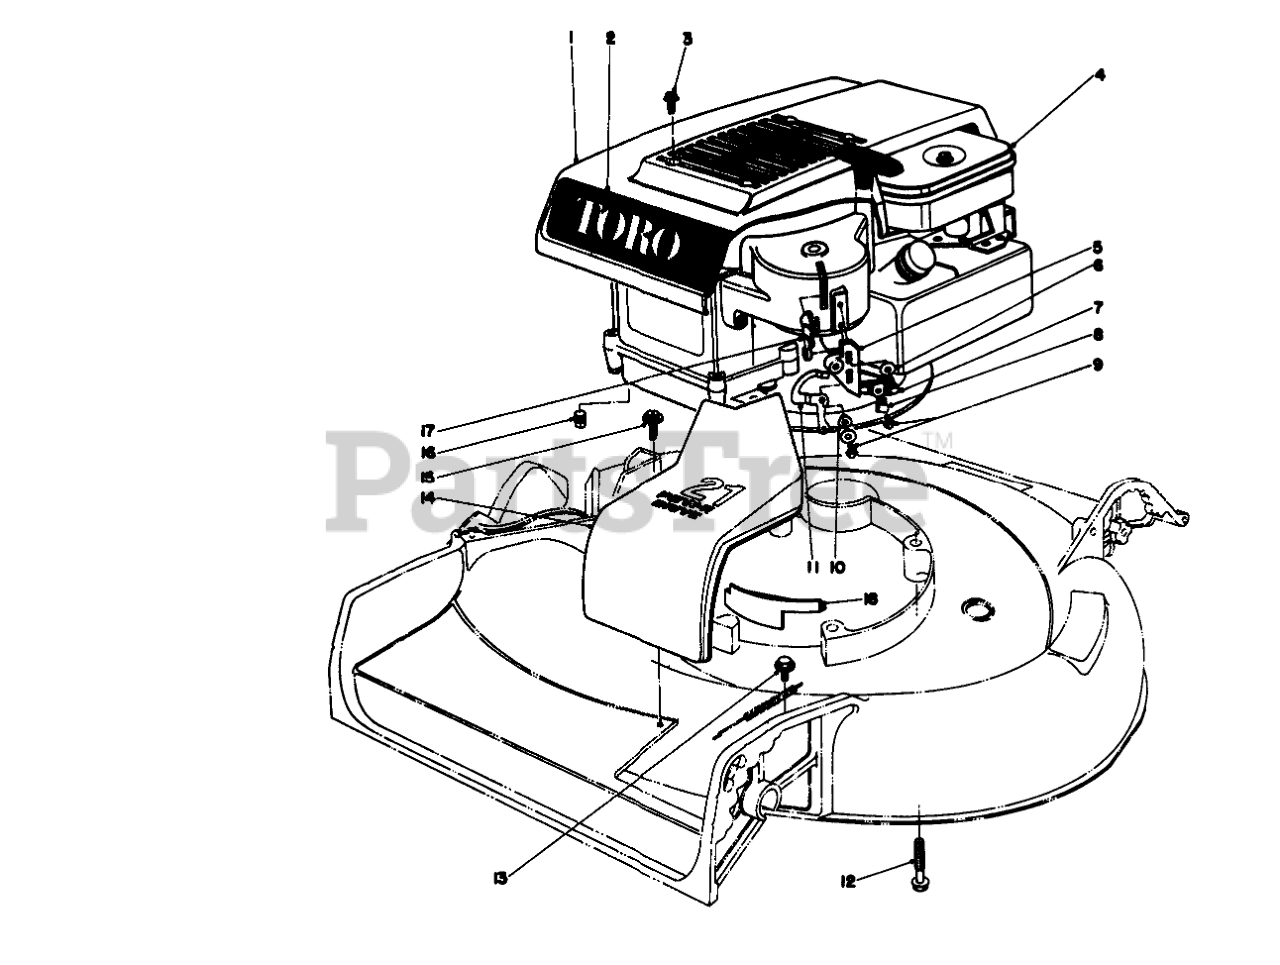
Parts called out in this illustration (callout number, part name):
1	SHROUD
2	Decal-Toro
4	Engine
5	Block Cable & Pivot
6	WASHER-FLAT
7	SCREW-SHWH
8	CLAMP
9	SCREW-HHFTF
10	BUSHING
11	CAM INTERLOCK
12	3/8-16 X 2-3/4 CAPSCR
13	SCREW-HWHTF
14	BELT DRIVE COVER
15	SCREW
16	PLUG-PIPE, SQH
17	INTERLOCK LEVER
18	HOUSING CAP
